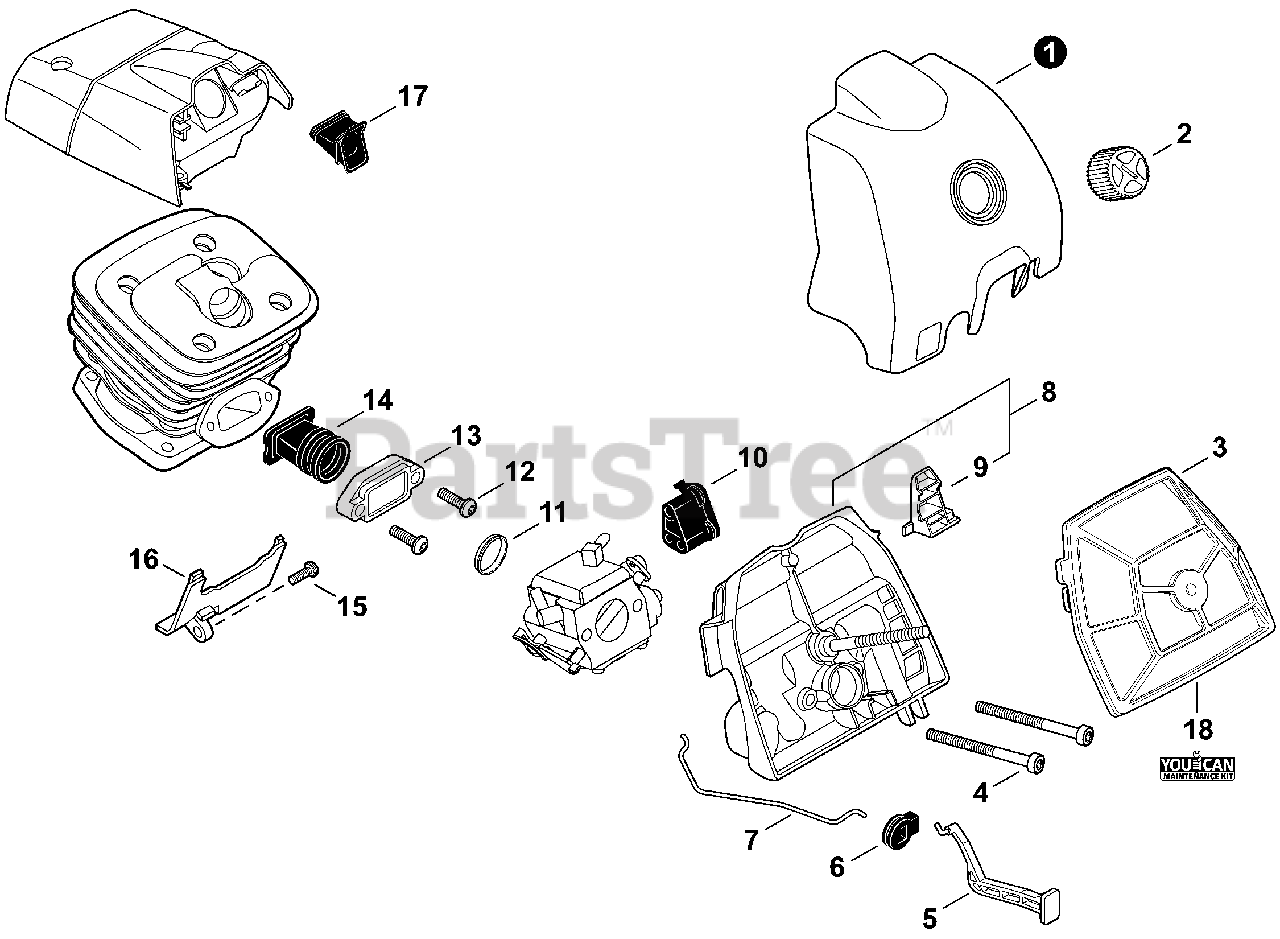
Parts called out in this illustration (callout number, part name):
1	COVER, AIR FILTER
2	KNOB, AIR FILTER COVER
3	FILTER ASSY, AIR
4	BOLT, TORX 5×50
5	ROD, CHOKE
6	GROMMET, CHOKE
7	ROD, THROTTLE
8	CASE ASSY, AIR FILTER
9	SHUTTER, AIR
10	GROMMET, NEEDLE
11	COLLAR 18.6×20.4×4
12	BOLT, TORX 5×16
13	HOLDER, BELLOWS
14	BELLOWS, INTAKE
15	BOLT, TORX 5×16
16	GUIDE, AIR
17	PIPE, INTAKE
18	TUNE-UP KIT - YOUCAN™
